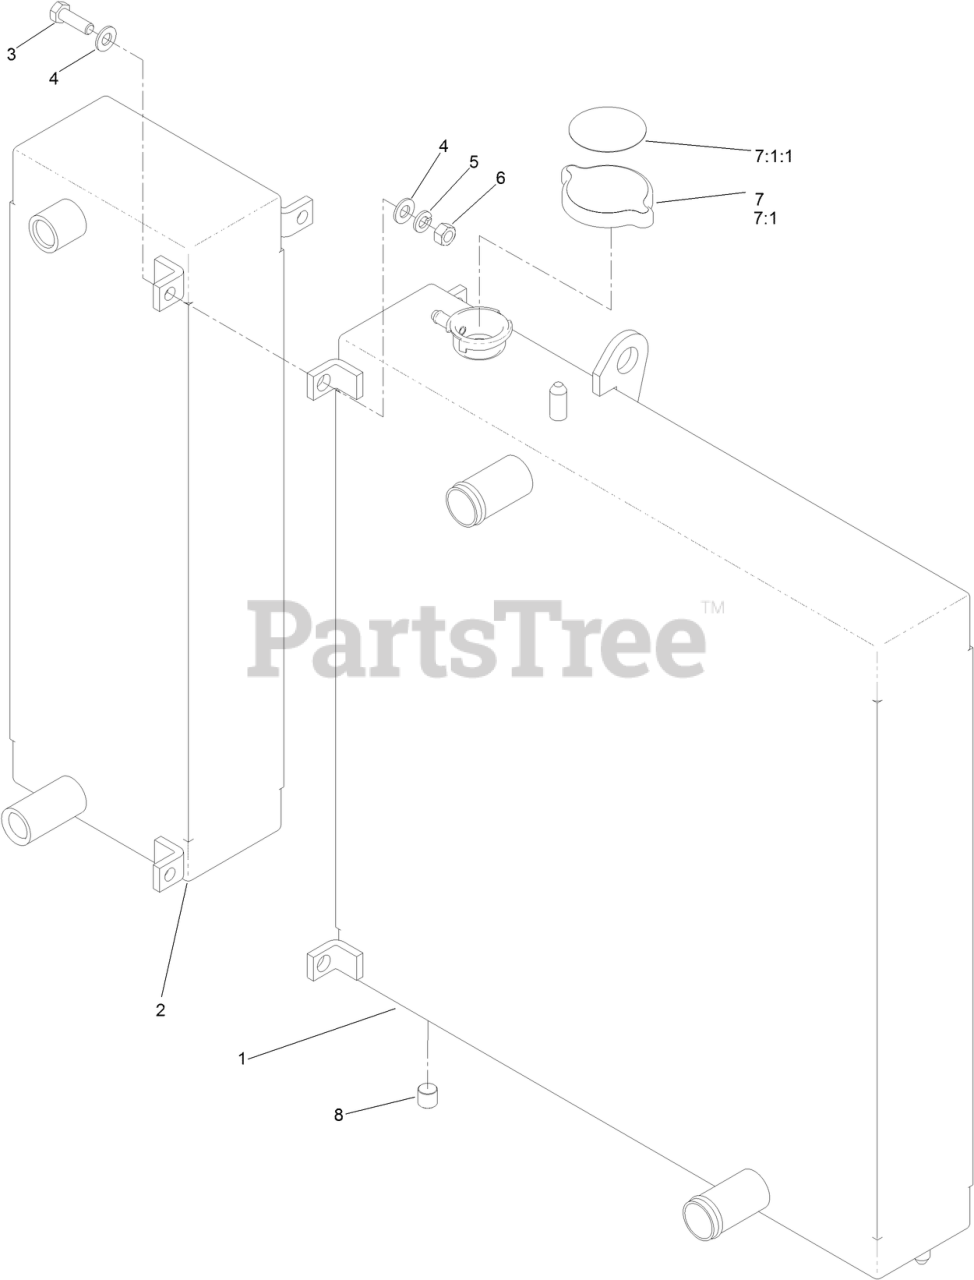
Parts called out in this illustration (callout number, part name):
1	RADIATOR
2	OIL COOLER
3	SCREW-HH
4	WASHER-PLAIN
5	WASHER-LOCK
6	NUT-HEX
7	RADIATOR CAP ASM
7:1	CAP-RADIATOR
7:1:1	DECAL-DANGER
8	PLUG-PIPE
